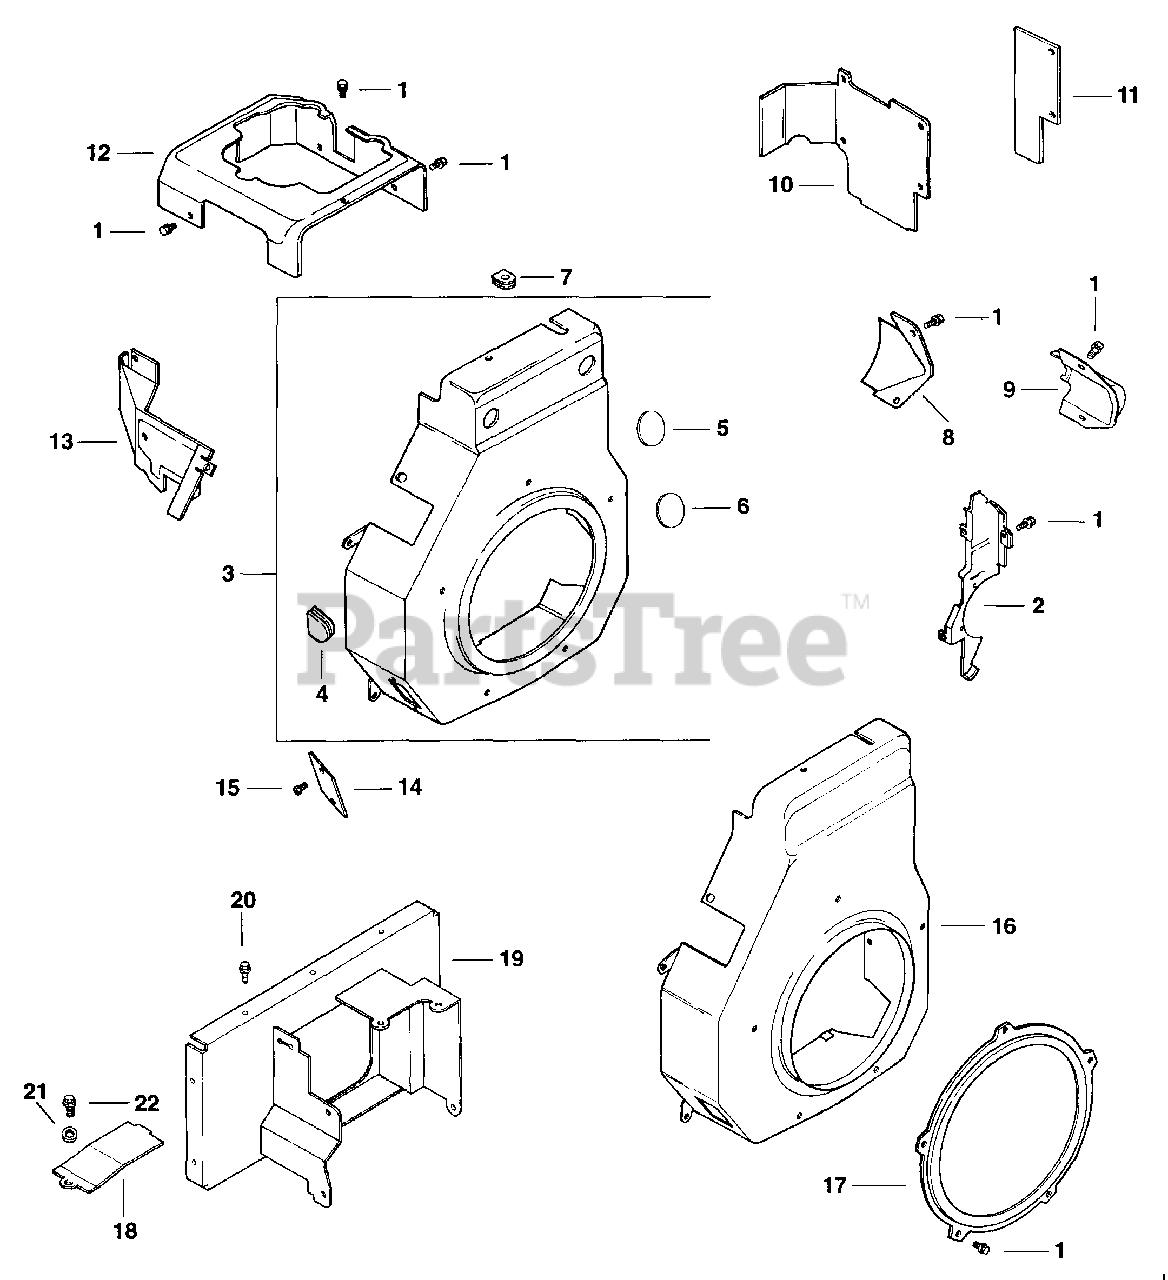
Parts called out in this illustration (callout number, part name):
1	SCREW - USE M-545010
2	PLATE, BACKING
3	HOUSING - USE 12 027 68
5	PLUG, BUTTON 9/16
6	PLUG, BUTTON 1/2
8	COVER
12	BAFFLE - USE 12 063 08-S
